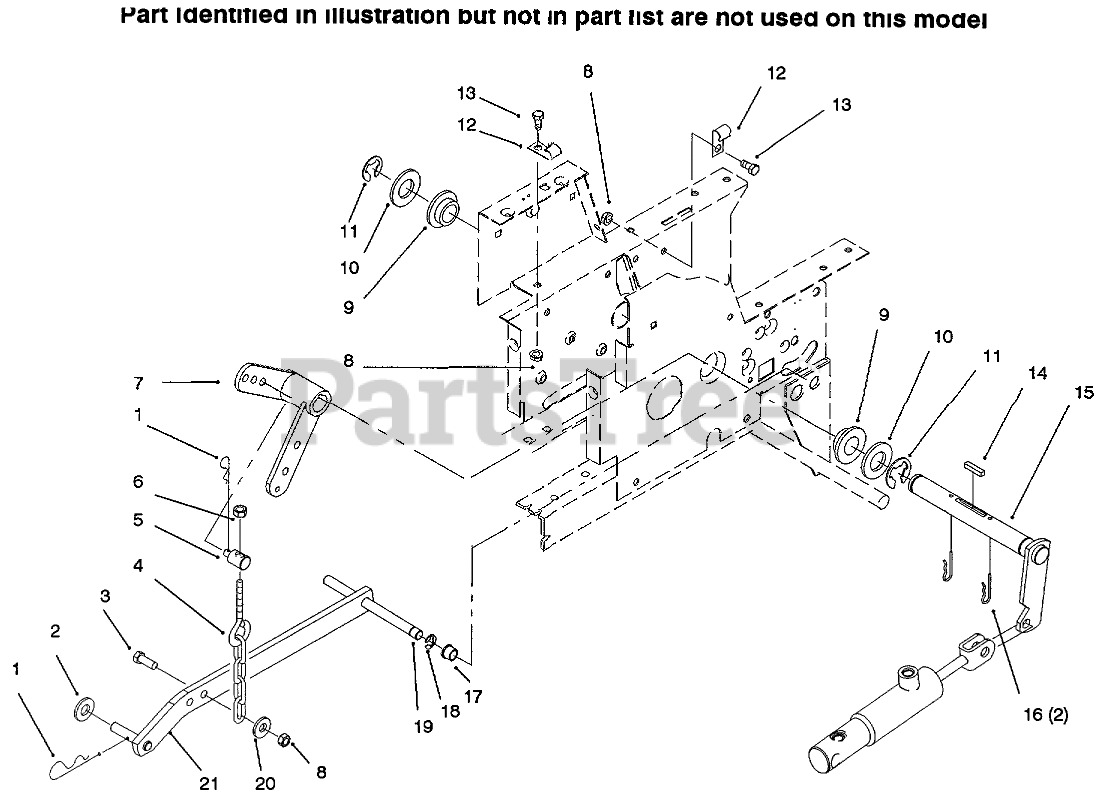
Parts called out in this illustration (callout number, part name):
1	PIN-HAIR
2	WASHER-FLAT
3	SCREW-HH
4	CHAIN-LIFT
5	TRUNNION
6	NUT-LOCK, NI
7	WLDMT-LIFT LEVER
8	NUT-LOCK, NI
9	BEARING-FLANGE
10	WASHER-FLAT
11	RING-RETAINING
12	CLIP
13	SCREW-HH
14	KEY-SQUARE
15	WLDMT-LIFT ARM
16	PIN-HAIR
17	BUSHING
18	RING-RETAINING, EXTERNAL
19	PIN-PIVOT
20	WASHER-PLAIN
21	Bar-Lift
